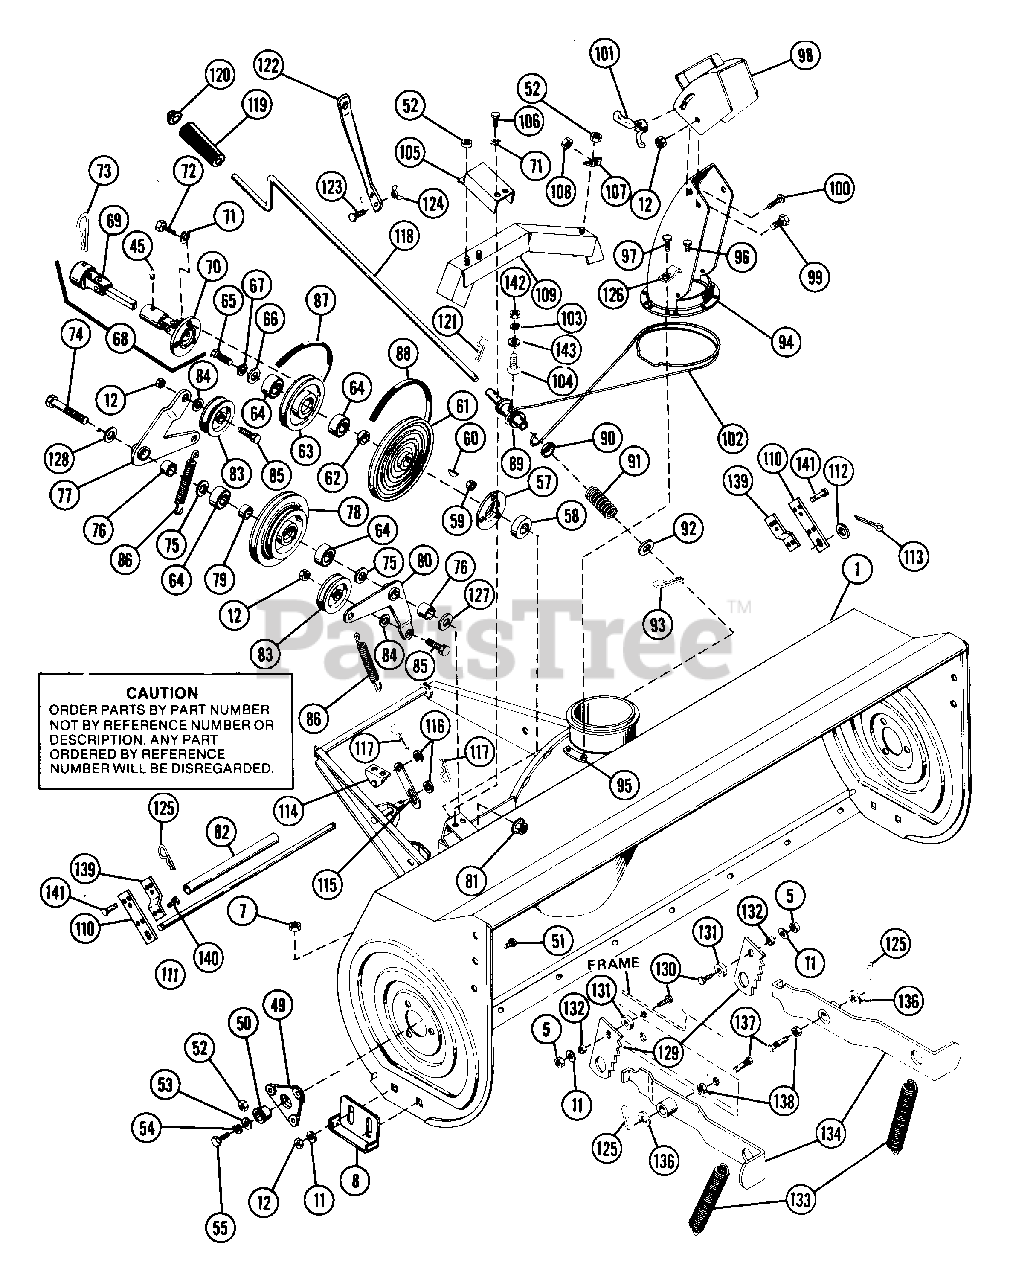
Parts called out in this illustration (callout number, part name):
1	BLOWER HOUSING ASSEMBLY
5	NUT-LK .312-18 GR A PL
7	NUT-LK TOP .375-16 GR C YWZC
8	SKID SHOE
11	WSHR-FL-STL .38X.875X.083 PL
12	NUT-LK-CTR .375-16 GR A PL
45	SPIN DRIVE ZERK FITTING
49	BEARING SUPPORT
50	BSHG-FLG 1.000X1.12X.62X1.50BR
51	SCR-SLTR-SERNK .25-20X.62 PL
52	NUT-LK-FLG .250-20 PL
53	WSHR-FL-STL .511X1.441X.125 PL
54	WSHR-LK .500X.151 HVY PL
55	BLT-HEX .50-13X1.00 PL GR2
57	BEARING FLANGE
58	BRG-BALL 1.0X2.0X.56
59	NUT-LK-CTR .250-20 PL
60	KEY-WDRF .188X.875X.375 SAE11
61	PLY-V 10.00 X .88 W/KEY SALEM
62	SPACER .906X1.125X.453
64	BRG-BALL .751X1.78X.61
65	BLT-HEX .38-16X1.00 PL
66	WSHR-FL-STL .438X1.0X.083 PL
67	WSHR-LK .375X.094 MED PL
68	UNIVERSAL SHAFT ASSEMBLY
69	UNIVERSAL SPLINE HALF
70	UNIVERSAL PLATE HALF
71	WSHR-LK .250X.077 HVY PL
72	BLT-HEX .25-20X.75 PL GR2
73	PIN-HAIR INT .18X1.18X3.25 PL
74	BLT-HEX .75-10X5.50 GR2
75	WSHR-FL-STL .755X1.375X.062 PL
76	BSHG-SLV .750X1.125X1.062
77	IDLER ARM
79	SPACER .781X1.000X.547
80	IDLER ARM
81	NUT-LK-FLG .75-10 GR F PL
82	TUBE .725 X .875 X 14.00
83	IDLER-FLAT 3.00 X .38 CLK.&CAP
84	WSHR-FL-STL .406X.875X.135
85	BLT-HEX .38-16X1.25 PL GR 2
86	SG-TENS 6.0 FREE LENGTH
87	V-BELT, HA-RAW EDGE
88	V-BELT, 4L-RAW EDGE
90	SPHERICAL WASHER
91	SG-COMP .054X.75X1.6
92	WSHR-FL-STL .641X1.250X.188
93	PIN-COTR .12 X 1.25 PL
94	CHUTE DISCHARGE
95	CHUTE CLAMP
96	SCR-TAP 10-24X.375 HWH PL TR
97	SCR-TAP 10-24X.75 HWH PL TR
98	SERVICE DEFLECTOR ASSEMBLY
99	BLT-HEX .38-16X.75 PL GR2
100	BLT-RDHDSQNK .38-16X.75 SHT PL
101	WING NUT
103	WSHR-LK .313X.062
104	BLT-RDHDSQNK .25-20X.62 PL
105	COVER
106	BLT-HEX .25-20X.50 PL GR2
108	NUT-FLG. .312-18 PL
109	BELT GUARD
110	LIFT LINK
112	WSHR-FL-STL .688X1.75X.134PL
113	PIN-COTR .12 X 1.25 PL
114	LIMITING POST
115	LIMITING ARM
116	WSHR-FL-STL .531X1.062X.095 PL
117	PIN-HAIR INT .09X.188 PL
118	CHUTE CRANK
120	CAP, 3/8 ROD YWZC
121	PIN-HAIR INT .08X.38X1.42 YWZC
122	CHUTE SUPPORT
123	BLT-RDHDSQNK .38-16X1.0 PL
124	NUT-WING .375-16 ZCC
125	PIN-HAIR INT .08X.18X1.18
126	CABLE CLAMP
127	WSHR-HDND-THRST .755X1.40X.062
128	WSHR-FL-STL .811X1.25X.025
130	BLT-HEX .31-18X1.25 PL GR2
131	SPACER .344X1.000X.375
132	SPACER BUSHING .5 X .32 X .21
133	SG-TENS .188X1.50X8.5 WLD 57
134	SPRING ARM
136	WSHR-FL-STL .458X.750X.06 PL
137	STUD-WEIGHT
138	NUT-LK-CTR .50-13
139	SUPPORT
140	BLT-SERHFWH .25-20X.50 PL
141	CLEVIS PIN
142	NUT-HEX .250-20 PL
143	WSHR-FL-STL.281X.62X.065 PL
